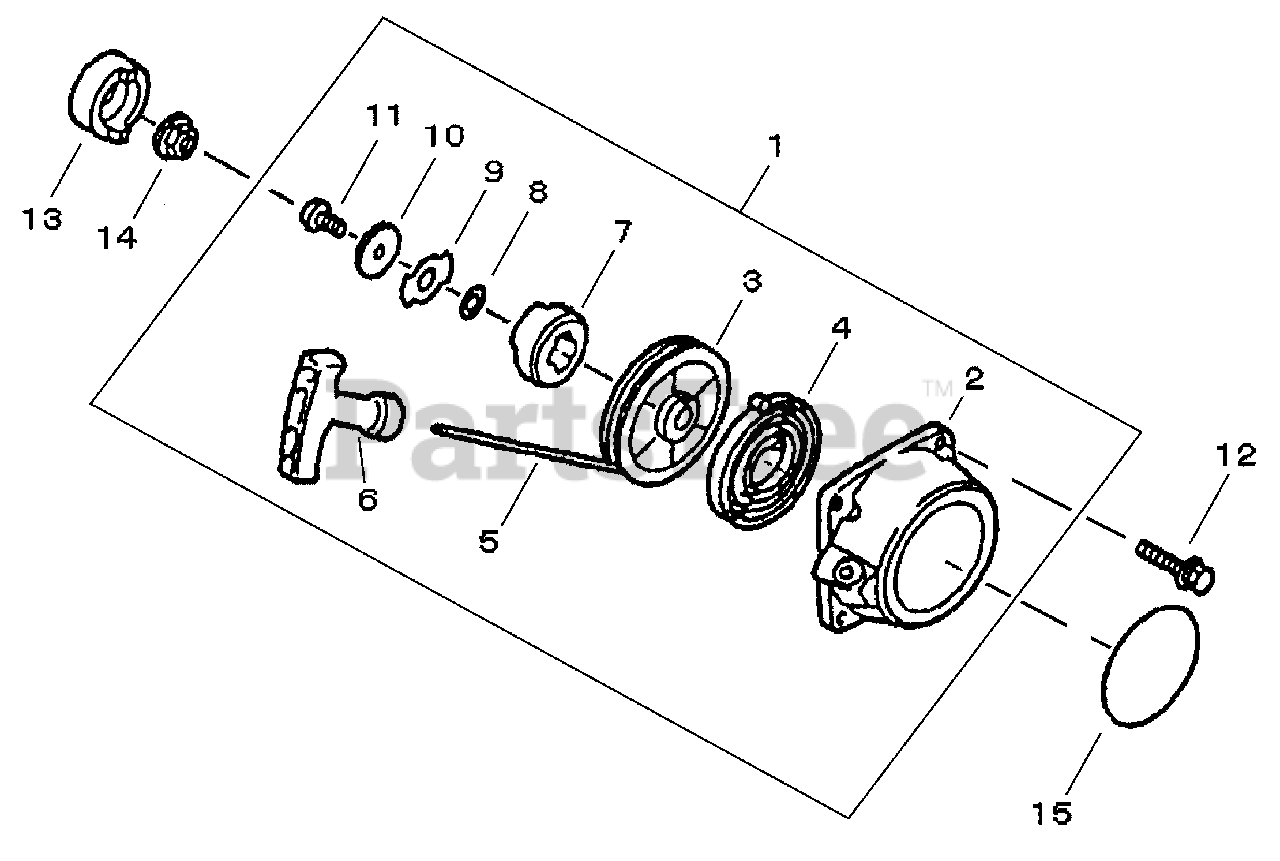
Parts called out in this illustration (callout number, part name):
1	STARTER ASSY
2	CASE, STARTER
3	REEL, ROPE
4	SPRING, REWIND
5	ROPE, STARTER
6	GRIP, STARTER
7	CATCHER, PAWL
9	RETAINER
11	SCREW - 8 X 1-1/4"
12	BOLT - 5X20
13	PAWL, STARTER
14	NUT - 10 -- FLANGE
15	LABEL - MODEL
